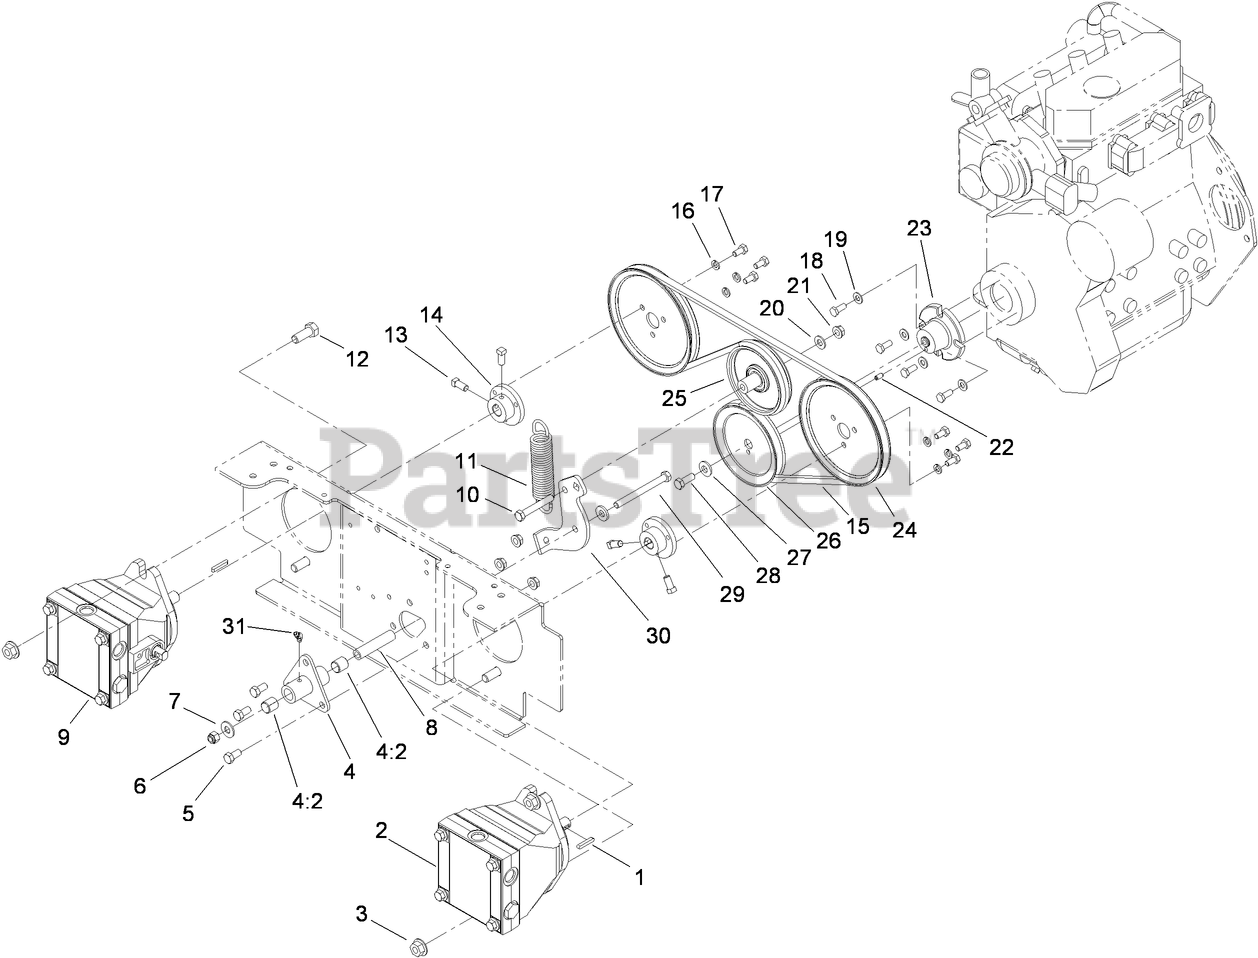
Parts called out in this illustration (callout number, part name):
2	PUMP-HYDRO, LH
3	NUT-HHF
4	PUMP IDLER ASM
4:2	SLEEVE-BEARING
5	SCREW-HH
6	NUT-LOCK, NI
7	WASHER-FLAT
8	BUSHING-TIGHTENER, PIVOT
9	PUMP-HYDRO, RH
10	SCREW-HH
11	SPRING-EXTENSION
12	SCREW-HH
13	SCREW-SET
14	HUB-PUMP
15	BELT-V
16	WASHER-LOCK
17	SCREW-HH
18	SCREW-HH
19	WASHER-PLAIN
20	WASHER-FLAT
21	NUT-HHF, WHIZ
22	PIN-ROLL
23	HUB-DRIVE, PUMP
24	SHEAVE-PUMP
25	IDLER-PUMP
26	SHEAVE-ENGINE
27	WASHER-BELLEVILLE
28	SCREW-HH
29	SCREW-HH
30	ARM-TIGHTENER, PUMP
31	FITTING-LUBE, 45 DEG
